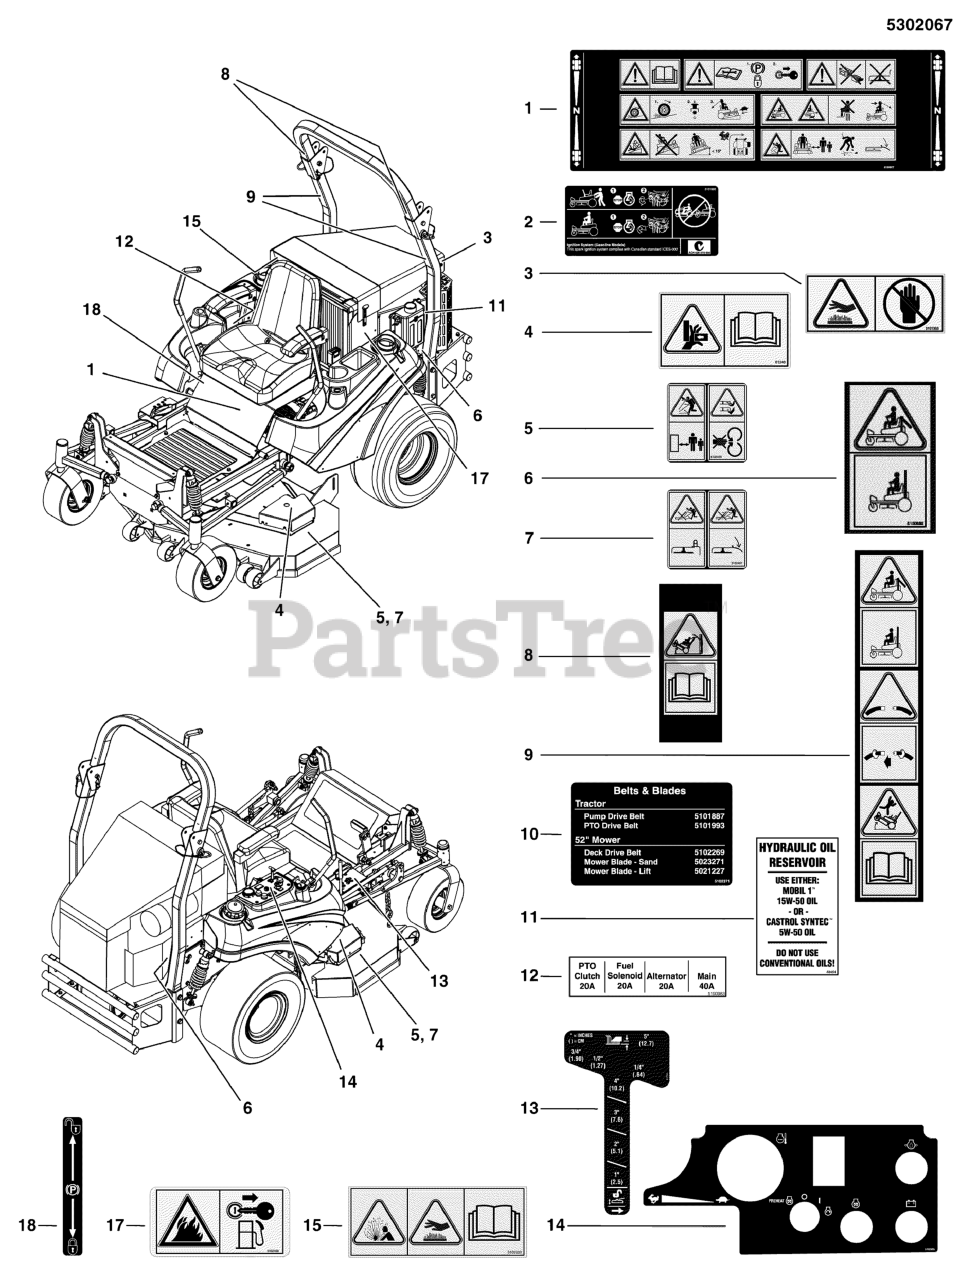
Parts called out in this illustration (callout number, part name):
1	DECAL, MAIN SAFETY, ANSI CE
2	DECAL, CZT HYRDO RELEASE
3	DECAL, HAND IN FLAME
4	DECAL, PINCH POINT, CE
5	DECAL, DANGER, MOWER DECK, ANSI EXP
6	DECAL, SAFTY, CE ROPS, OBS
7	DECAL, DANGER DISCHARGE ANSI EXP
8	DECAL, WARNING, ROLL BAR, CE
9	DECAL, SAFETY, CE ROPS
11	DECAL, OIL RESEVOIR
12	DECAL, FUSE LOCATION
13	DECAL-HEIGHT CITATION
14	DECAL, DASH, S175X
15	DECAL, WARNING, HOT
17	DECAL, FIRE ANSI EXPORT
18	DECAL, PARKING BRAKE SYMBOLS
